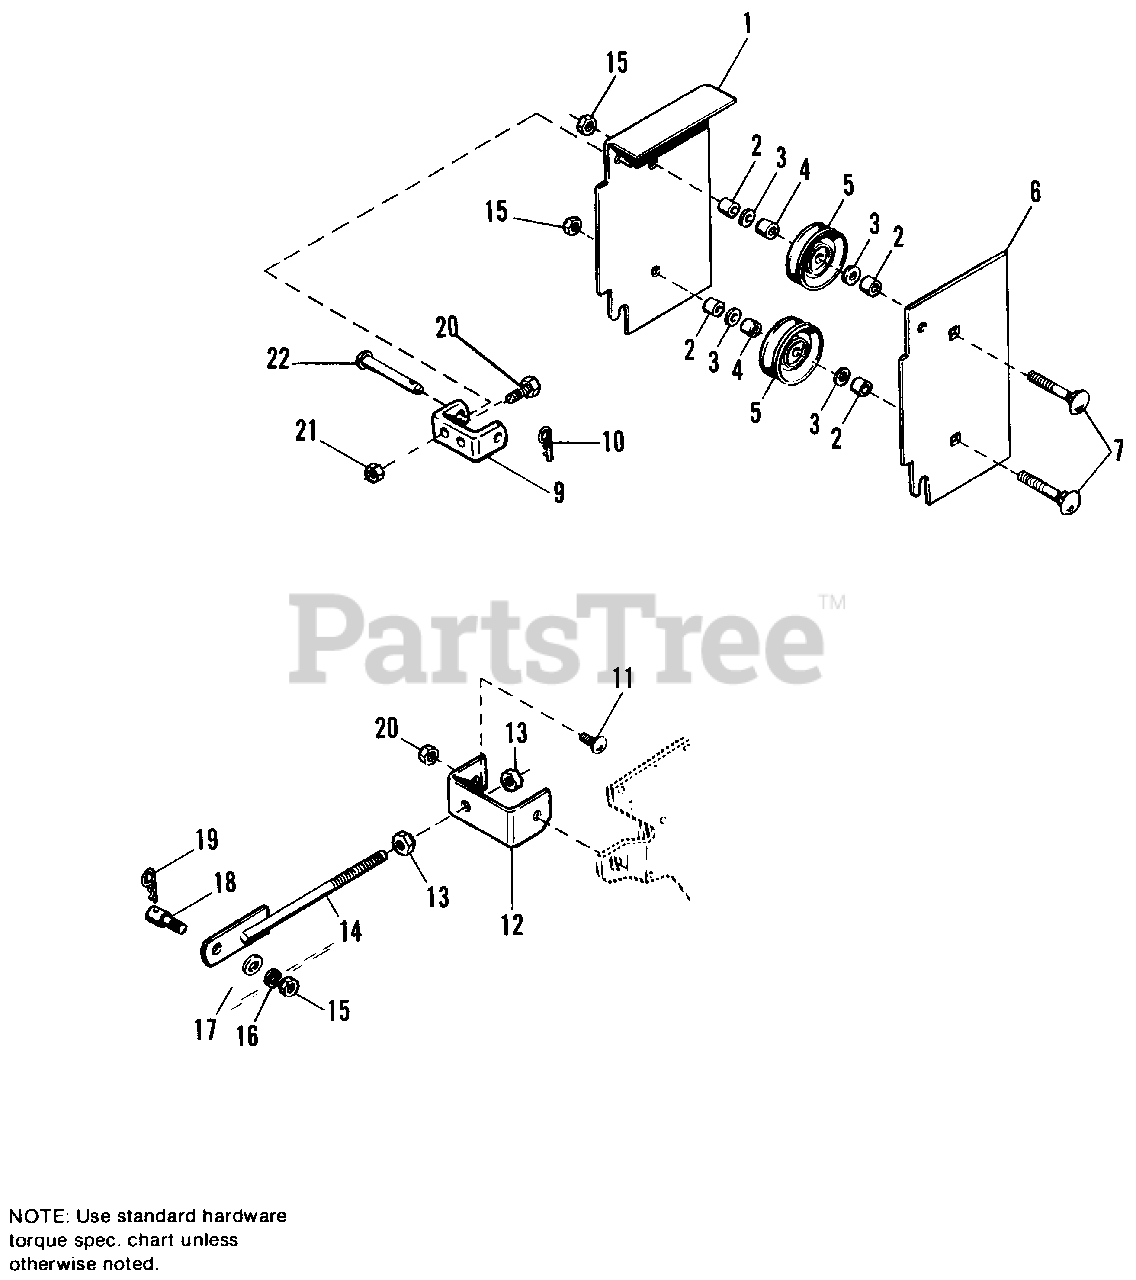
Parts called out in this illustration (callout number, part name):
1	GUARD, Pulley, R.H.
3	WASHER, Flat, 3/8 x 7/8 x 14
5	PULLER ASSY.
6	GUARD, Pulley, L.H.
7	BOLT, 5/8 x 15 x 2-1/4
8	BOLT, Hex Hd., 5/16-18 x 7/8, Gr.5
9	BRACKET, Guard
10	PIN
11	CARRIAGE BOLT, 3/8 x 3/4
12	CLEVIS, Mast
13	NUT, Hex, Jam, 1/2-20
14	ARM, Mast Assy.
15	NUT, Hex, 3/8-16
16	LOCKWASHER, 3/8
17	WASHER, 3/8 x 1 x 1/8
20	NUT, Hex, 3/8-16
21	NUT, Hex, 5/16-18
22	PIN, Guard Bracket
